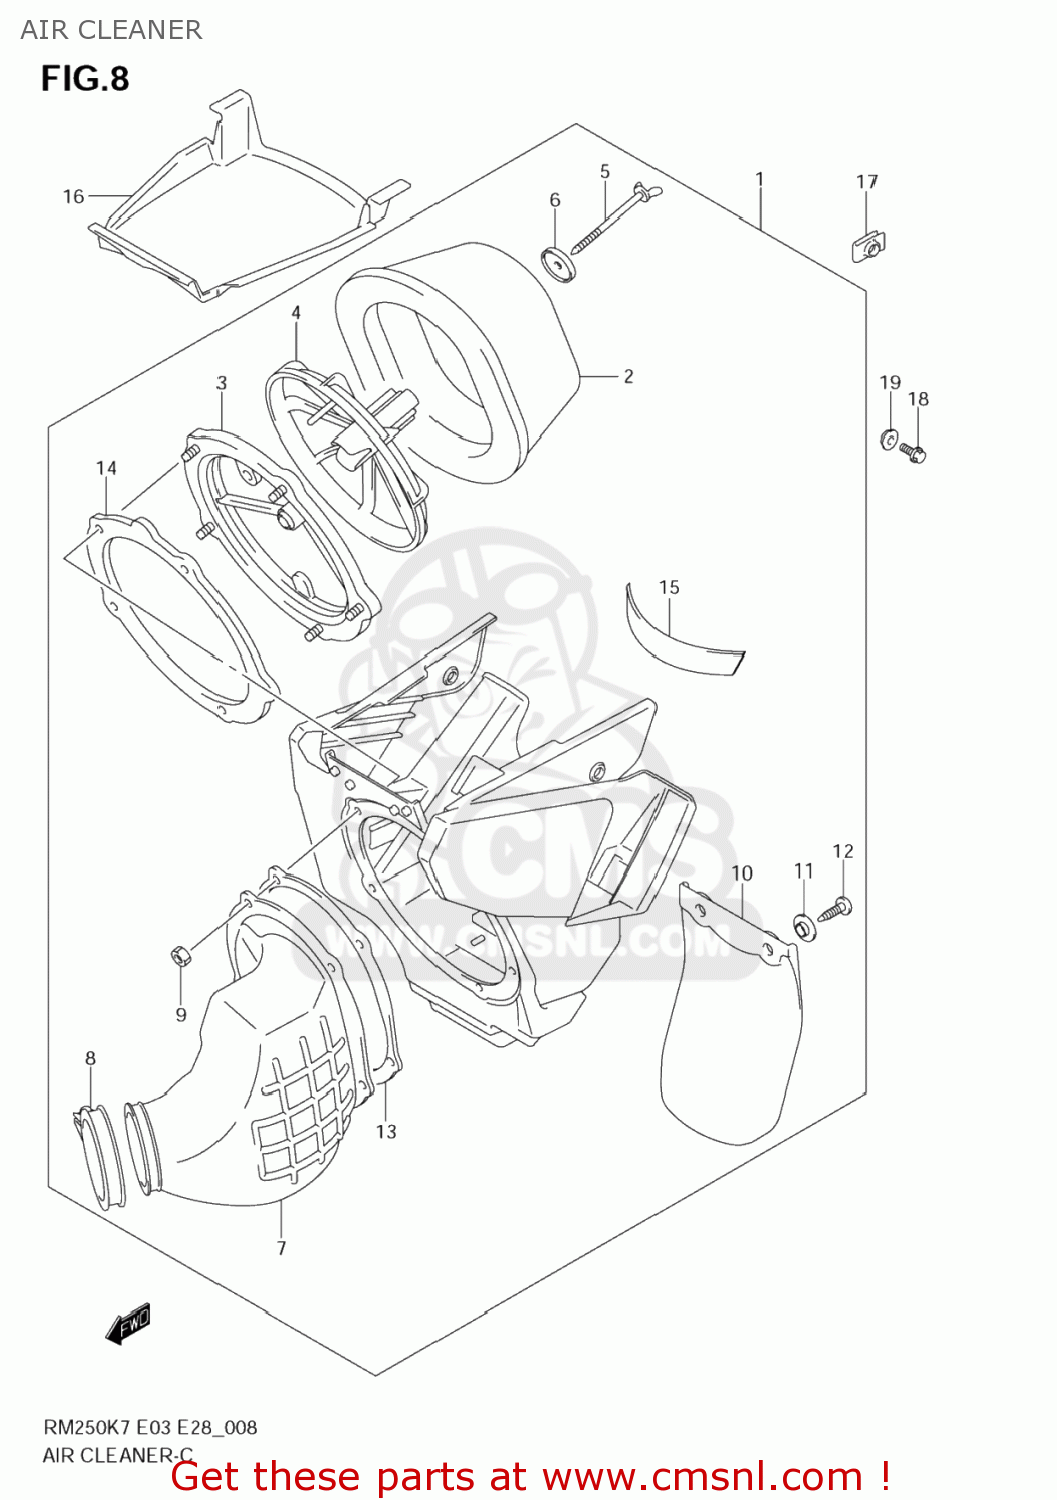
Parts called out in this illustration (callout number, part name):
1	CLEANER ASSY,AIR
2	FILTER ASSY
3	BASE,FILTER
4	HOLDER,FILTER
5	BOLT,WING
6	WASHER,AIR CLEANER
7	TUBE,OUTLET
8	CLAMP
9	NUT
10	MUDGUARD
11	COLLAR
12	SCREW
13	PLATE
14	GASKET (NAS)
15	CUSHION,AIR CLEANER
16	CAP,AIR CLEANER
17	NUT
18	BOLT(6X10)
19	WASHER
